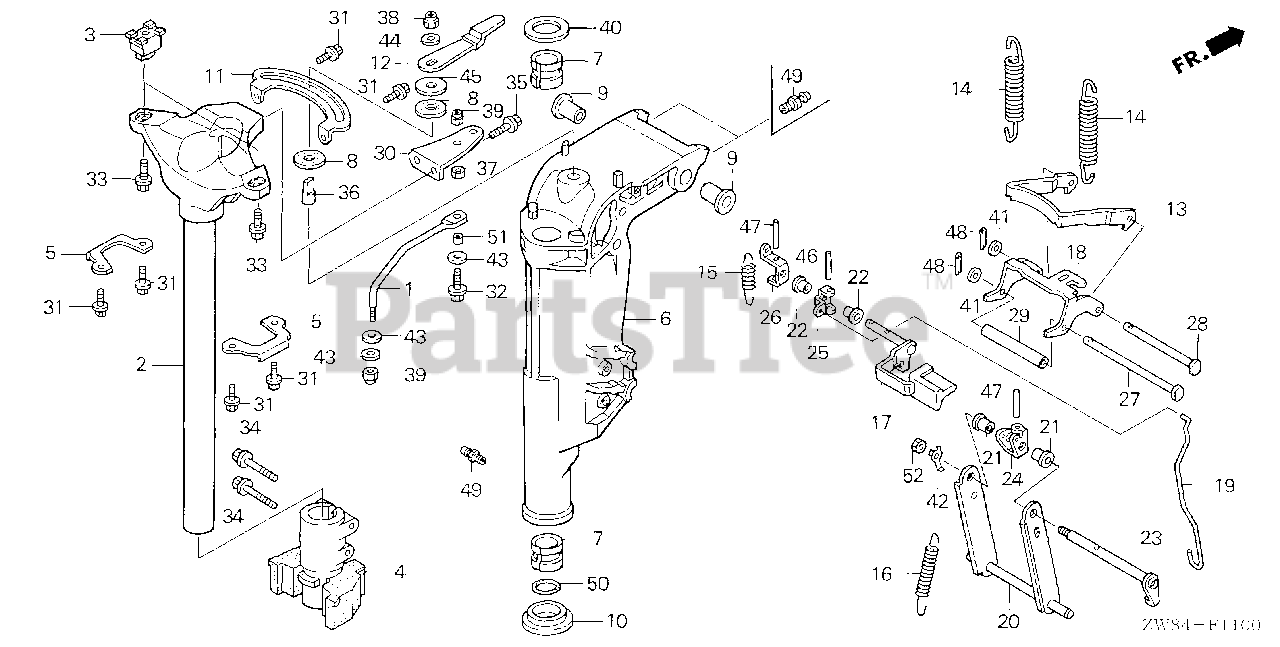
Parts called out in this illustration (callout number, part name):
1	ROD, STEERING
2	FRAME, MOUNTING (L)
3	RUBBER, MOUNTING (UPPER)
4	RUBBER, MOUNTING (LOWER)
5	COVER, MOUNTING RUBBER (UPPER)
6	CASE, SWIVEL *NH282MU* (L) (OYSTER SILVER METALLIC-U)
7	LINER, SWIVEL CASE
9	BUSH, SWIVEL CASE
10	COLLAR, SWIVEL CASE
13	HOOK, REVERSE LOCK
14	SPRING, REVERSE LOCK
15	SPRING, TILT LEVER
16	SPRING, TILT LINK
17	LEVER, TILT
18	ARM, REVERSE LOCK
19	ROD, RELEASE SWIVEL CASE
21	BUSH, TILT LEVER
22	BUSH, TILT LEVER
23	SHAFT, TILT
24	BRACKET, TILT SHAFT
25	BRACKET, RELEASE ROD
26	BRACKET, TILT LEVER
27	SHAFT, REVERSE LOCK (A)
28	SHAFT, REVERSE LOCK (B)
29	COLLAR, REVERSE LOCK
30	PLATE, STEERING
31	BOLT, FLANGE (6X12)
32	BOLT (3/8-24 UNF)
33	BOLT, FLANGE (10X25)
34	BOLT, FLANGE (8X45)
35	BOLT, FLANGE (10X20)
37	NUT (3/8-24 UNF)
39	NUT, SELF-LOCK (3/8-24UNF)
40	WASHER, THRUST
41	WASHER, PLAIN (6MM)
42	WASHER, LOCK
43	WASHER (10MM)
46	PIN, SPRING (3.0X22)
47	PIN, SPRING (3.0X25)
48	PIN, SPLIT (2.0)
49	NIPPLE, GREASE
50	O-RING (34X2.4)
51	COLLAR, STEERING ROD
52	NUT, HEX. (6MM)
